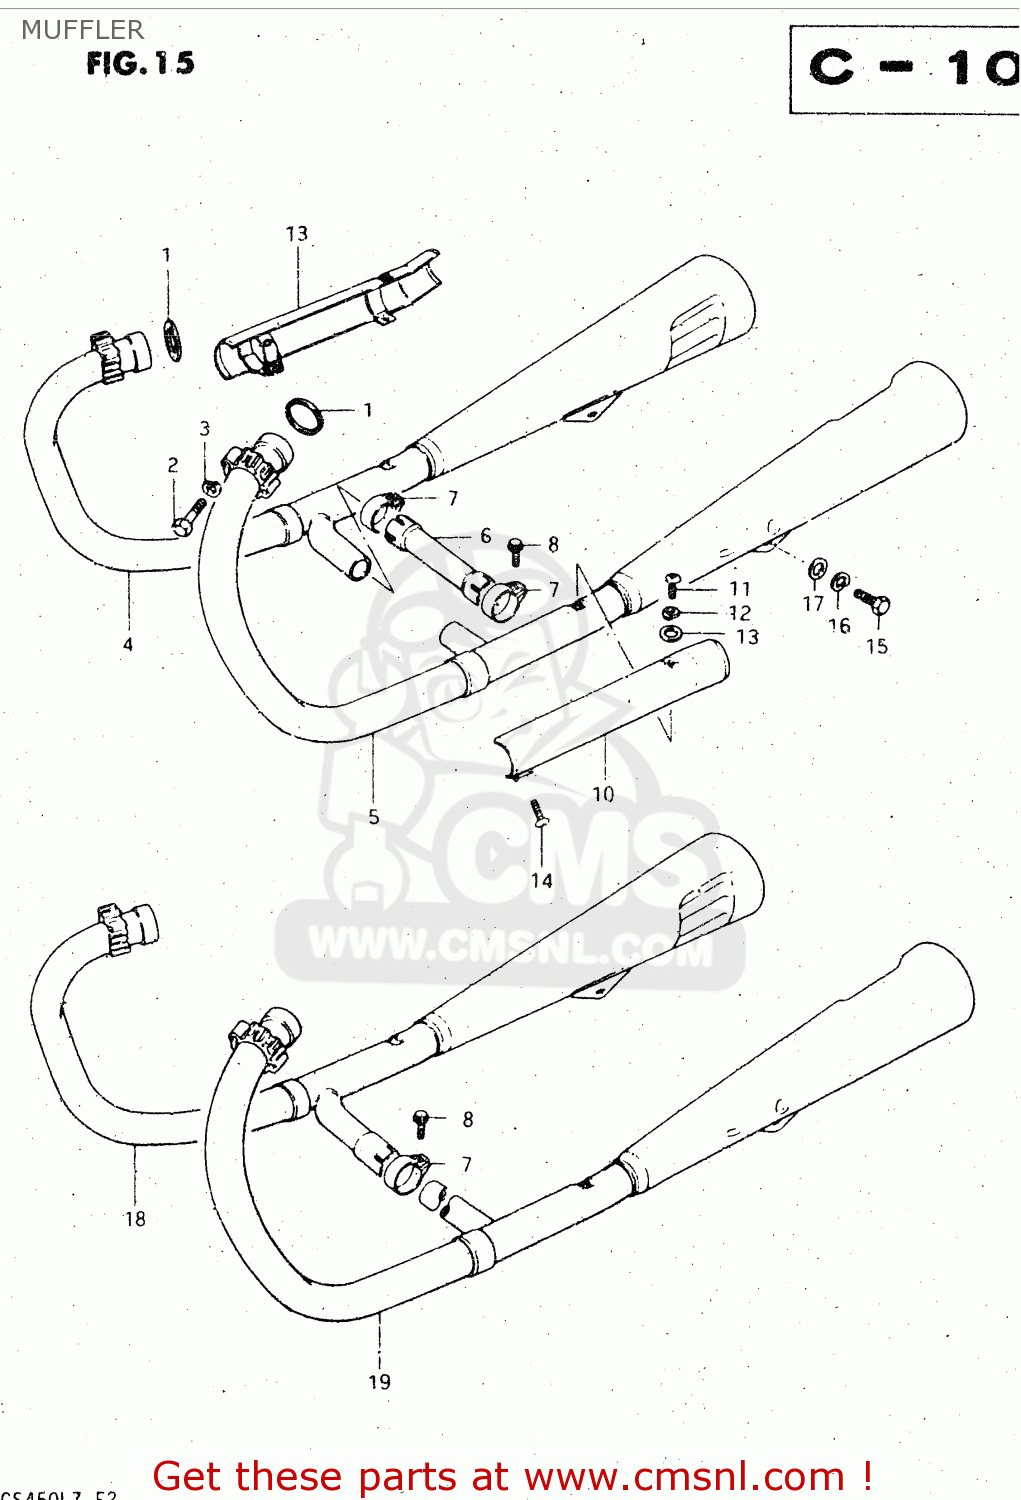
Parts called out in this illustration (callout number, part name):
1	GASKET,EXHAUST PIPE (NAS)
2	BOLT
3	LOCK WASHER
4	MUFFLER, RH
5	MUFFLER, LH
6	PIPE,EXHAUST COUPLER
7	CLAMP
8	BOLT
9	COVER,MUFFLER
10	COVER,MUFFLER
11	SCREW
12	LOCK WASHER
13	WASHER
14	SCREW
15	BOLT 10X25
16	LOCK WASHER
17	WASHER
18	BODY,MUFFLER
19	BODY,MUFFLER
